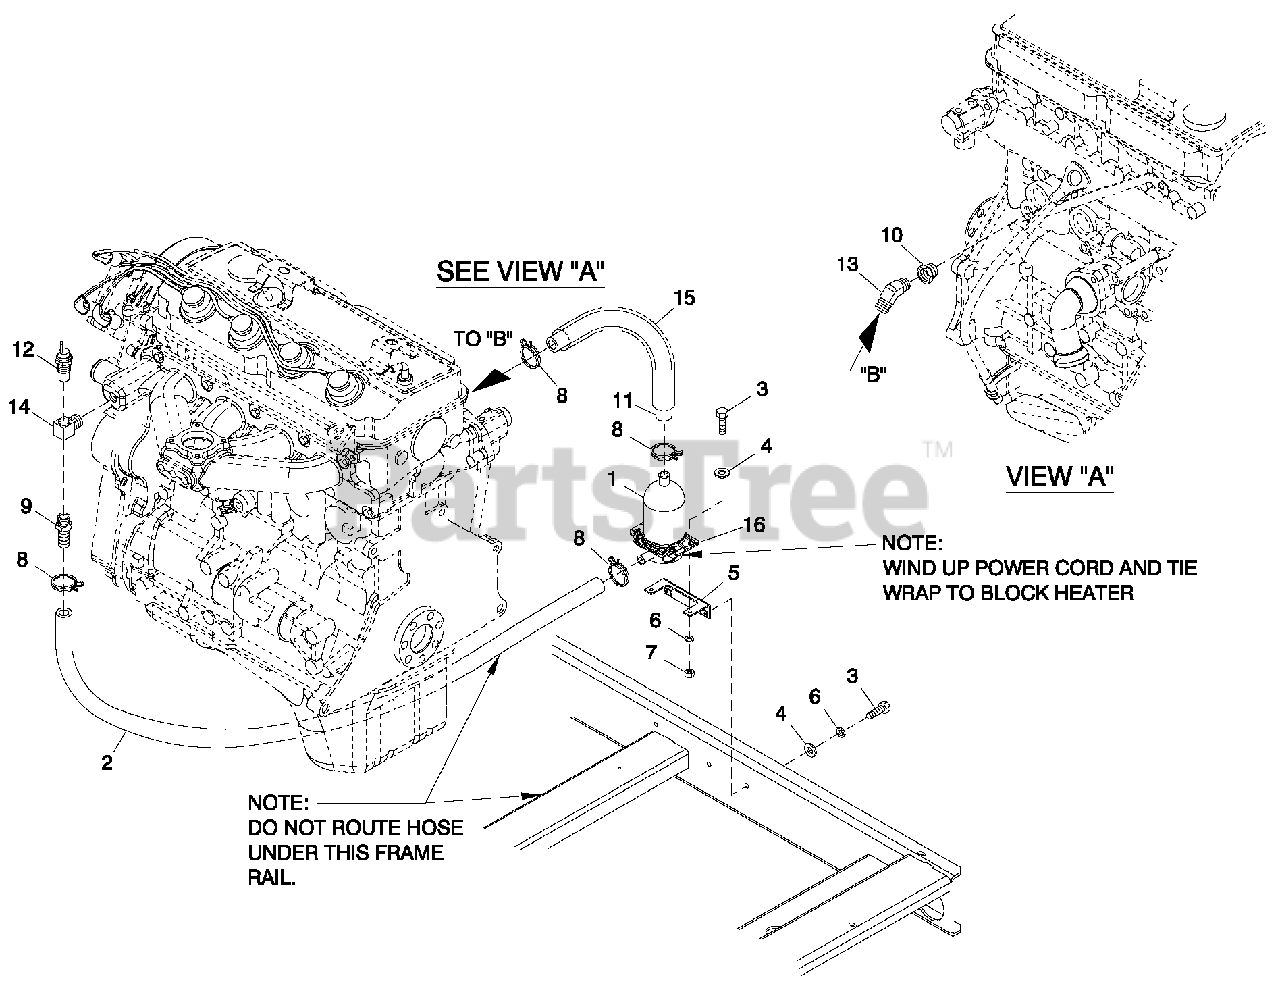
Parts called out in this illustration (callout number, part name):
1	HEATER BLOCK 1500W 120V
2	HOSE COOL 5/8 ID 20R3 (37" LG)
3	SCREW HHC M6-1.0X 20 G8.8
4	WASHER FLAT 1/4- M6 ZINC
5	BRACKET HEATER W/WELDNUTS
6	WASHER LOCK M6-1/4
7	NUT HEX M6X 1.0 G8YEL CHR
8	CLA MP HOSE 7/8" OD DOUBLE WIRE
9	BARBED STR 3/8NPTX 5/8
10	ADAPTER 3/8 BSPT M X 3/8 NPT F
11	HOSE COOL 5/8 ID 20R3 (13" LG)
12	SWITCH HI-TEMP 245D X 3/8NPT
13	BARBED EL 45 3/8NPT X 5/8OD
14	TEE BRANCH 3/8NPT F MF BRASS
15	CONDUIT FLEX 1.0"ID (13" LG)
16	TIE WRAP UL 7.4"X .19" BLK
17	CONDUIT FLEX 1.0"ID (37" LG)
